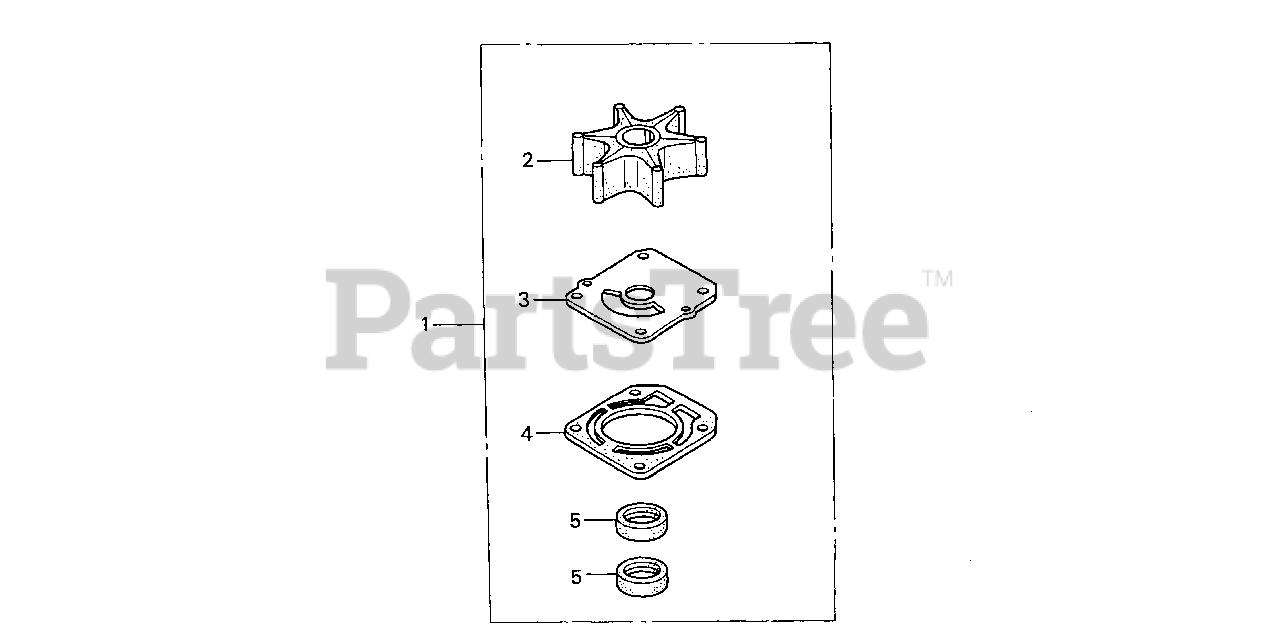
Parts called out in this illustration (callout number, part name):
1	IMPELLER KIT, WATER PUMP Use up to Frame SN 4004682.
1	IMPELLER KIT, WATER PUMP
2	IMPELLER, PUMP
3	GASKET B, IMPELLER
4	GASKET, WATER PUMP
5	SEAL, WATER (23X36X6) Use up to Frame SN 4004682.
5	SEAL, WATER (23X36X6)
